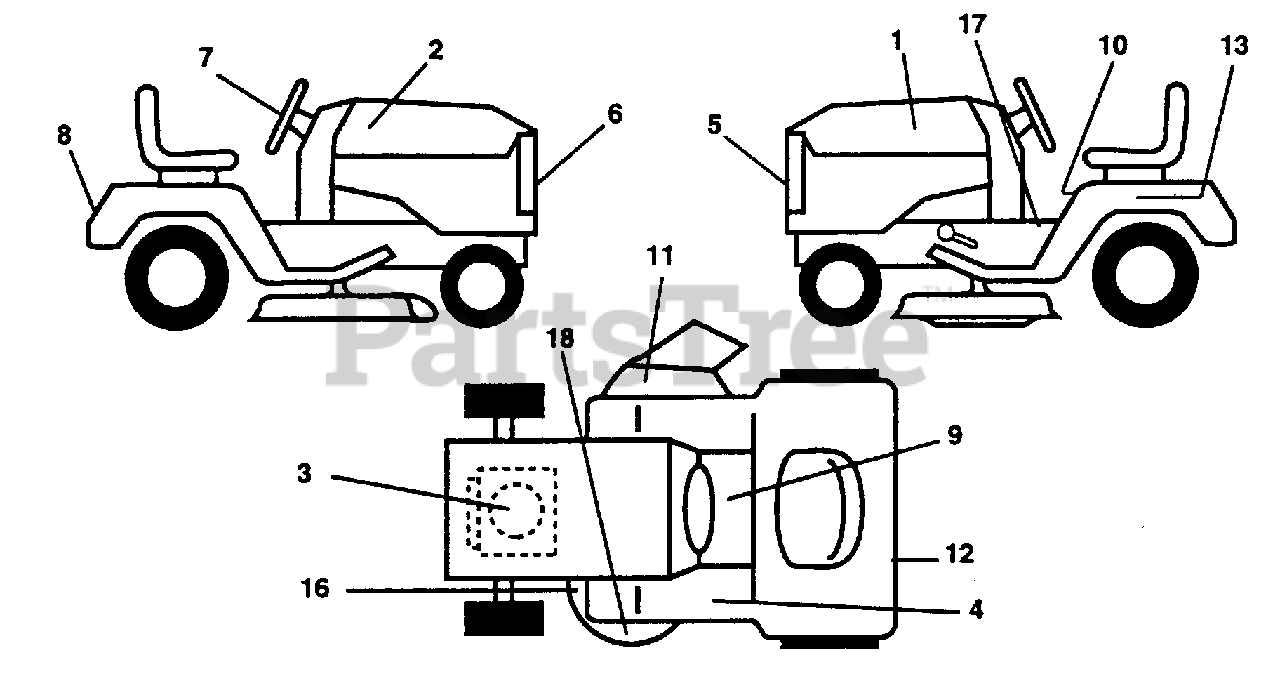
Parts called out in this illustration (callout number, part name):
1	Decal, Hood, L. H.
2	Decal, Hood, R. H.
3	Decal, Engine HP
4	Decal, Height Indicator
6	Decal, Lightbox
7	Decal, Insert, Stg. Whl.
8	Decal, Fender
9	Decal, Cold Start
10	Decal, Caution, Fender
11	Decal, Warning, Cut Finger, (Multi-Lang)
12	Decal, Drawbar
13	Decal, Caution, Battery
16	Decal, V-Belt Sch.
17	Decal, Inst. Oper.
18	Decal, Deck Enviro
